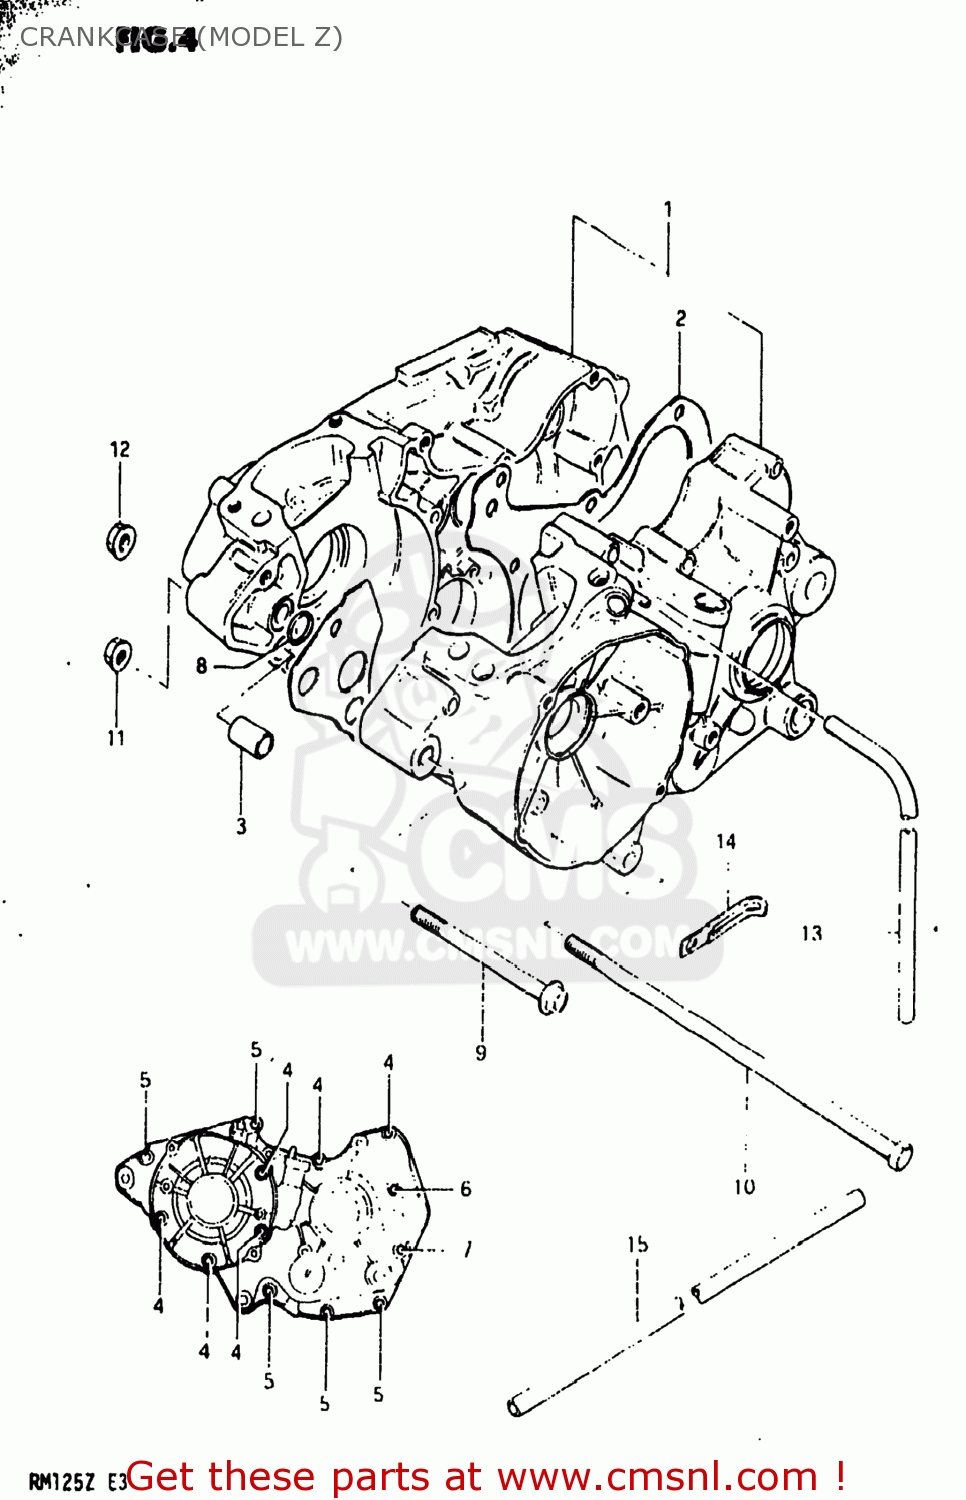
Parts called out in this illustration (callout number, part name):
1	CRANKCASE SET
2	GASKET,CRANKCASE (MCA)
3	PIN
4	SCREW (6X45)
5	SCREW
6	SCREW
7	SCREW 6X65
8	O RING(D:1.9,ID:13.8)
9	BOLT 8X90
10	BOLT 8X205
11	NUT
12	NUT
13	HOSE
14	CLAMP
15	HOSE
